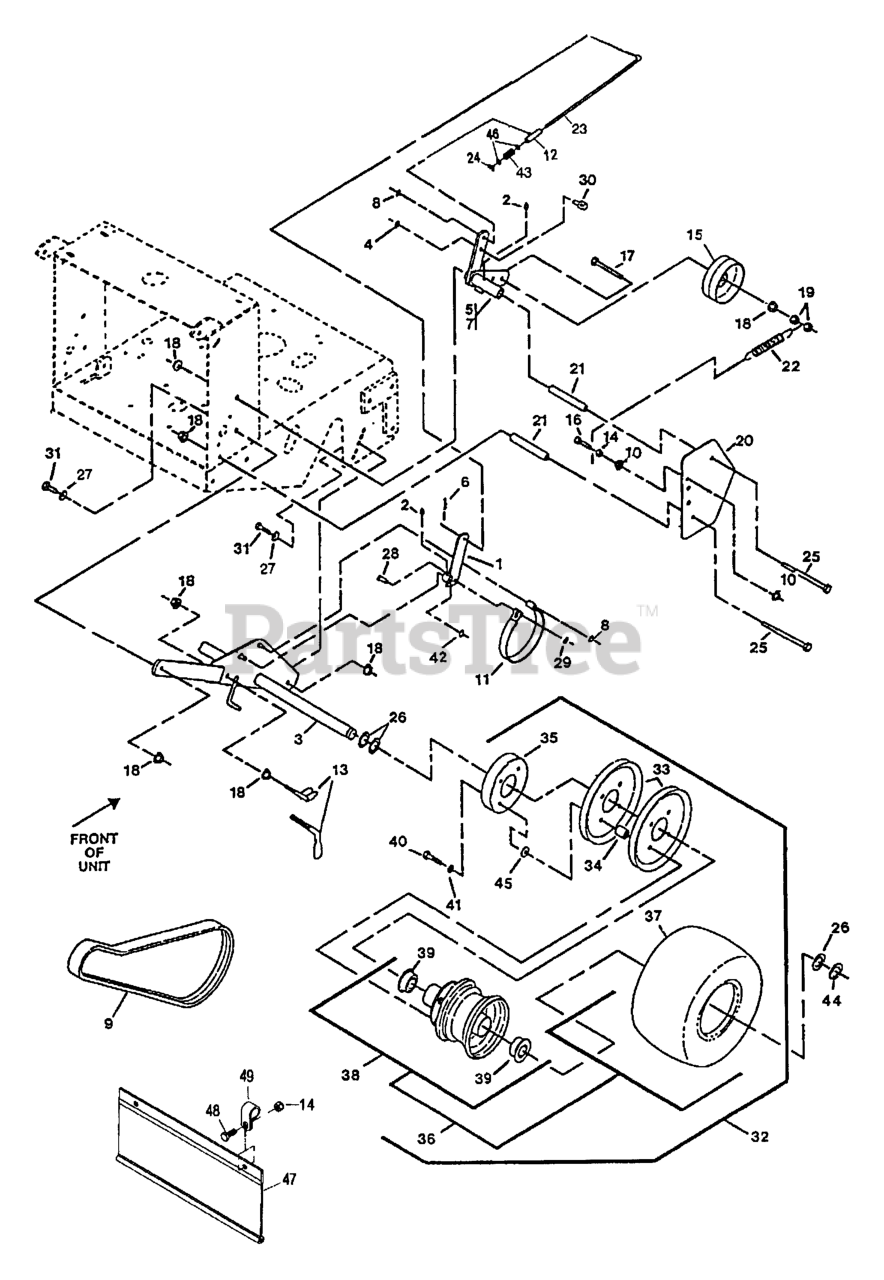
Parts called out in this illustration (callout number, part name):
2	FITTING-GREASE
3	AXLE
4	RING-CLIP
6	PIN-COTTER
8	RING-RETAINING
9	BELT,WHEEL DRIVE
11	BAND-BRAKE
13	SCRAPER
14	NUT-LOCK, NI
15	IDLER-WHEEL, DRIVE
16	SCREW-HH
17	SCREW-HH
18	NUT-HHF, WHIZ
19	NUT-LOCK, NI
20	SHIELD-WHEEL, DRIVE
21	SPACER-SHIELD
22	SPRING-EXTENSION
23	LINKAGE-BRAKE
24	WINGNUT-NYLOCK
25	SCREW-HH
26	WASHER-SPACER
27	WASHER-BELLEVILLE
28	PIN-CLEVIS
29	RING-RETAIN,PUSH,EXT,FLAT
30	SWIVEL-SHORT, ADJUSTABLE
31	SCREW-HH
33	SHEAVE-WHEEL, DRIVE
34	SPACER-SHEAVE, WHEEL
35	DRUM-BRAKE
36	WHEEL AND TIRE ASM
37	TIRE-TURFMASTER
38	WHEEL AND HUB ASM
39	BEARING-FLANGED
40	SCREW-HH
41	WASHER-LOCK
42	RING-RETAINING, EXTERNAL
43	SPRING-COMPRESSION
44	RING-SNAP
45	WASHER
46	WASHER-PLAIN
47	SHIELD-TRAILING
48	SCREW-HH
49	CLAMP-R
